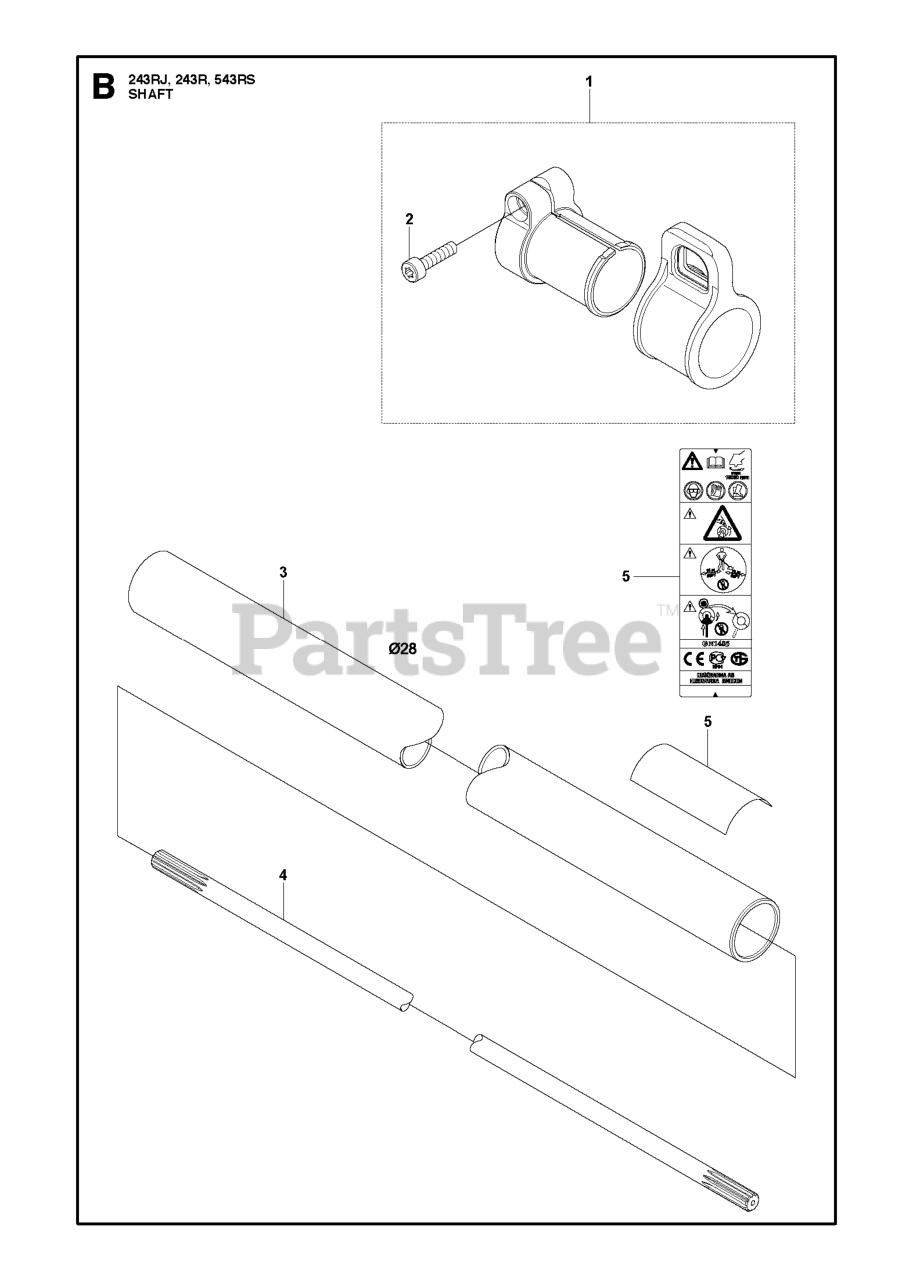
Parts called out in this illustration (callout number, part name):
1	HANGER ASSY.
2	RP BOLT TORX M5XL20 T27
4	SHAFT 848JJC58E0
5	DECAL
